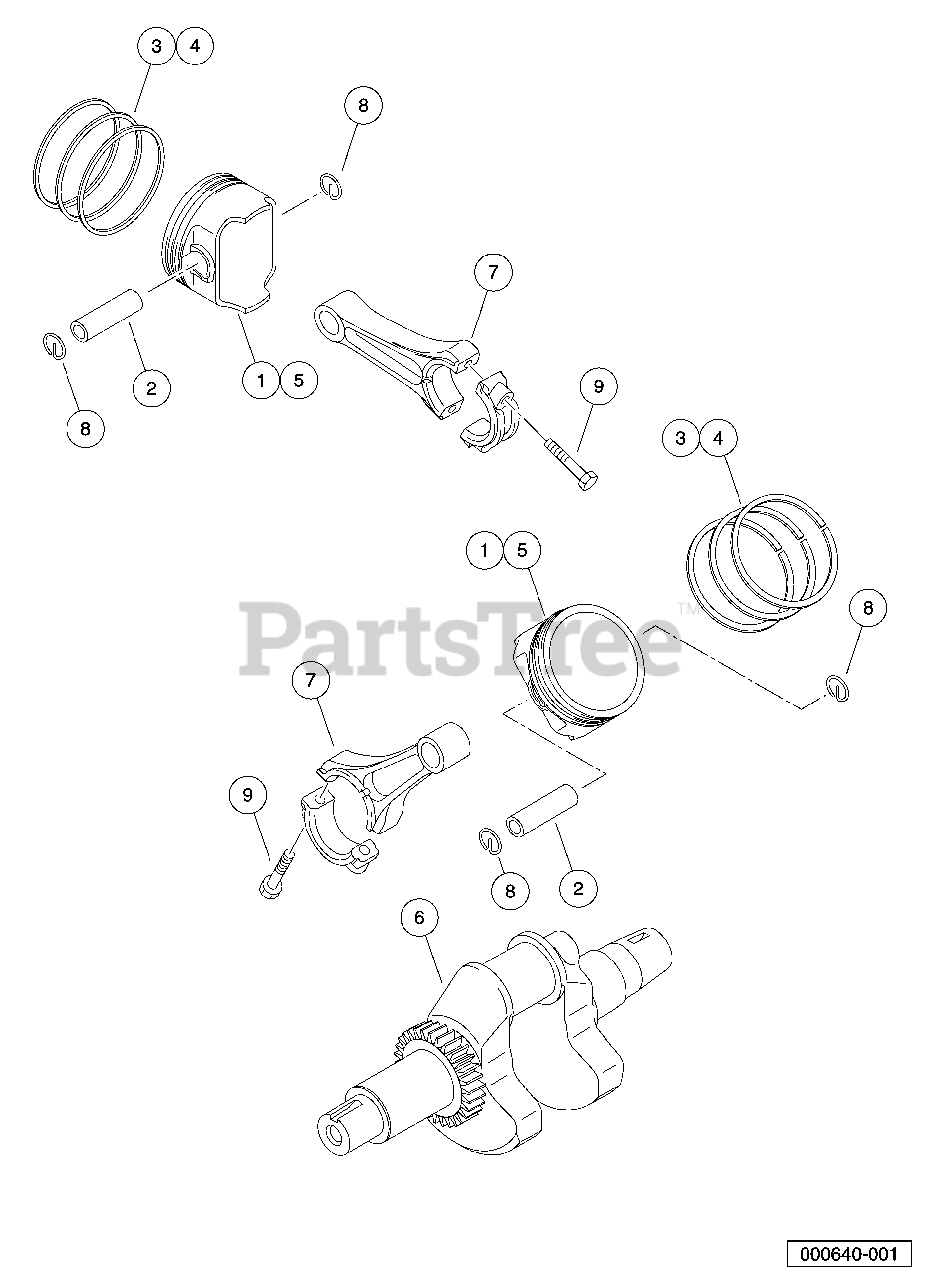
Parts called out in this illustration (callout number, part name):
1	Piston, Engine, Right, Fh
2	Pin, Piston, Engine, Fh
3	Ring, Set, Piston, Fh
4	Ring, Set, Piston L, 050, Fh
5	Piston, Engine L, 050, Fh
6	Crankshaft, Comp, Fh
7	Kit, Rod, Connecting, Fh
8	Ring, Snap, Pin, Piston, Fh
9	Bolt, Flg, M6 X 100 X 35
